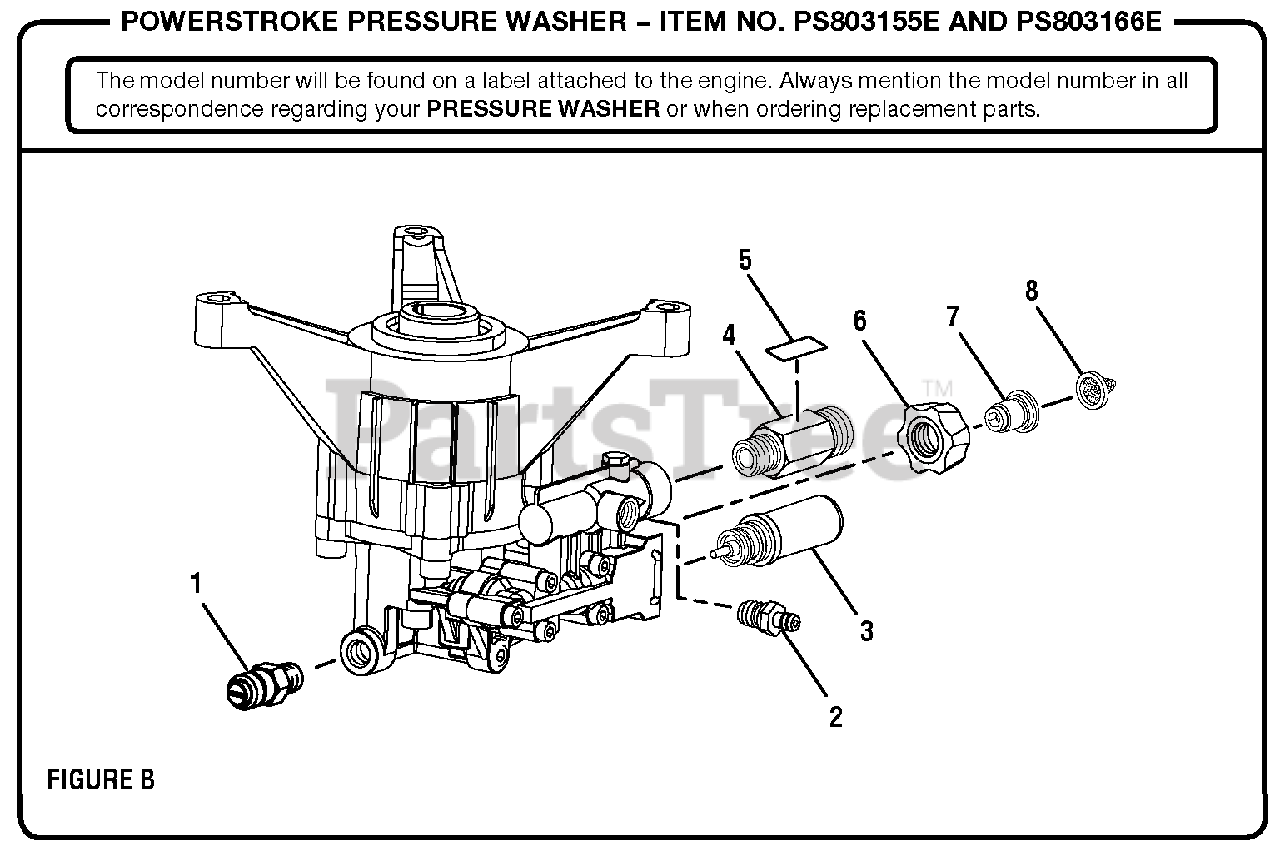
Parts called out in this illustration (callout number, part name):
1	Thermal Release Valve
2	Soap Injector Kit
3	Unloader Valve Assembly
4	Outlet Tube
5	Hose Outlet Label
6	Inlet Filter Adapter
7	Inlet Filter Connector
8	Inlet Filter Screen
